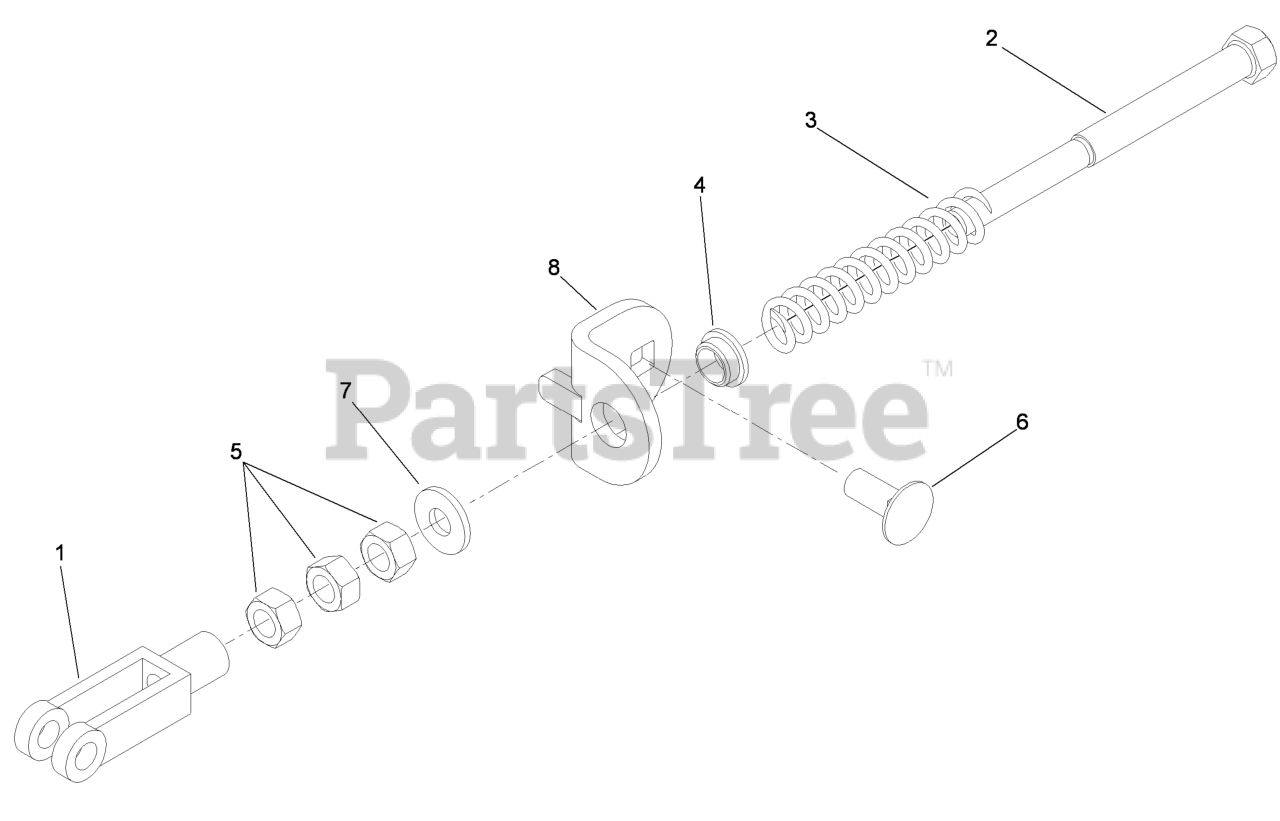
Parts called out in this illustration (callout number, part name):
1	YOKE-ADJUSTABLE
2	BOLT-RETURN, NEUTRAL
3	SPRING-RETURN, NEUTRAL
4	BUSHING-NYLON, FLANGED
5	NUT-HEX
6	SCREW-CARR
7	WASHER-FLAT
8	TAB-ADJUSTMENT
